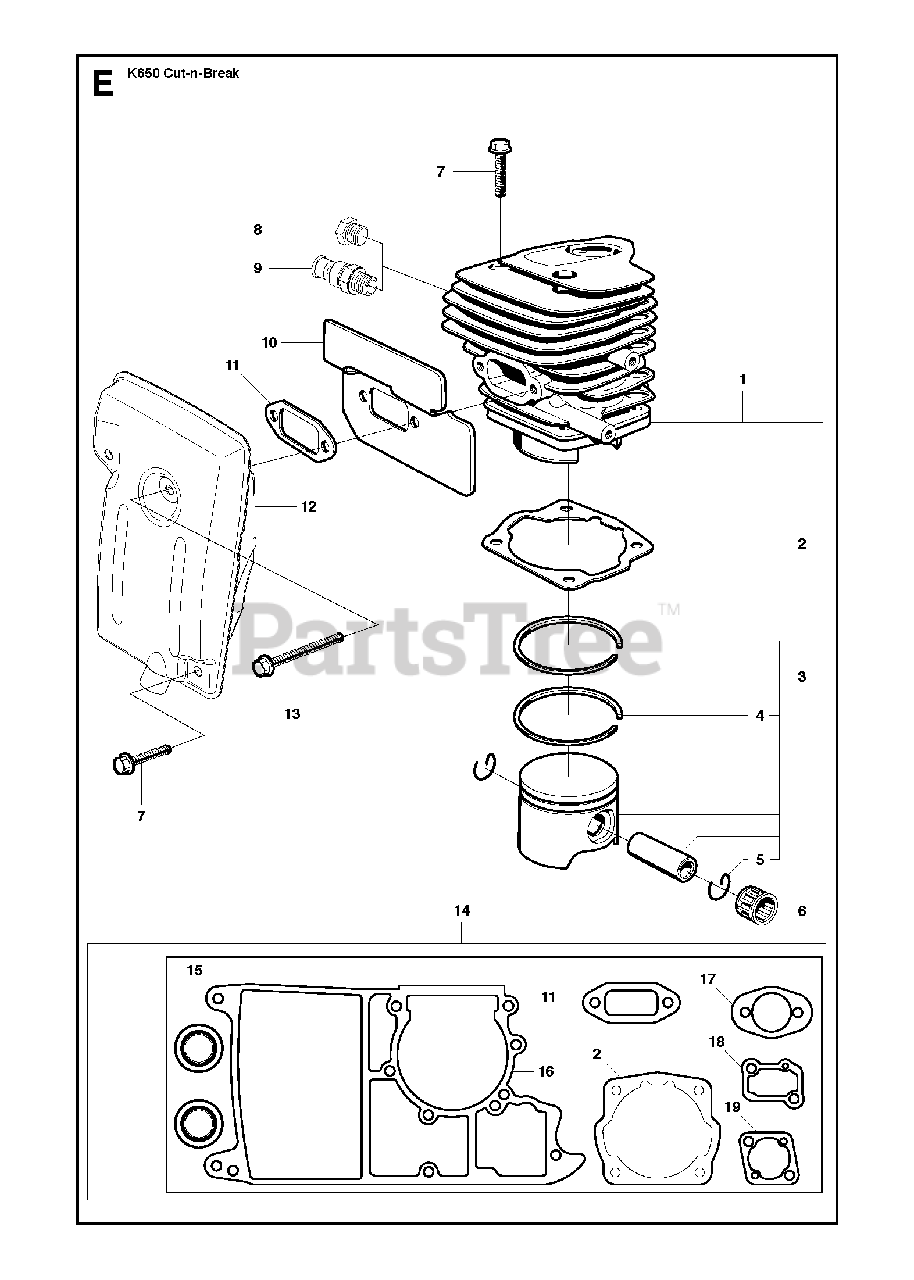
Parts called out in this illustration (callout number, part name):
1	CYLINDER ASSYIncl. 2, 3, 6
2	GASKETGasket kit 14
3	PISTON ASSYIncl. 4, 5
6	NEEDLE BEARING
7	SCREW EHHFM
9	DECOMPRESSION VALVE
14	GASKET KITIncl. 2, 11, 15 - 19
15	SEALING RING
